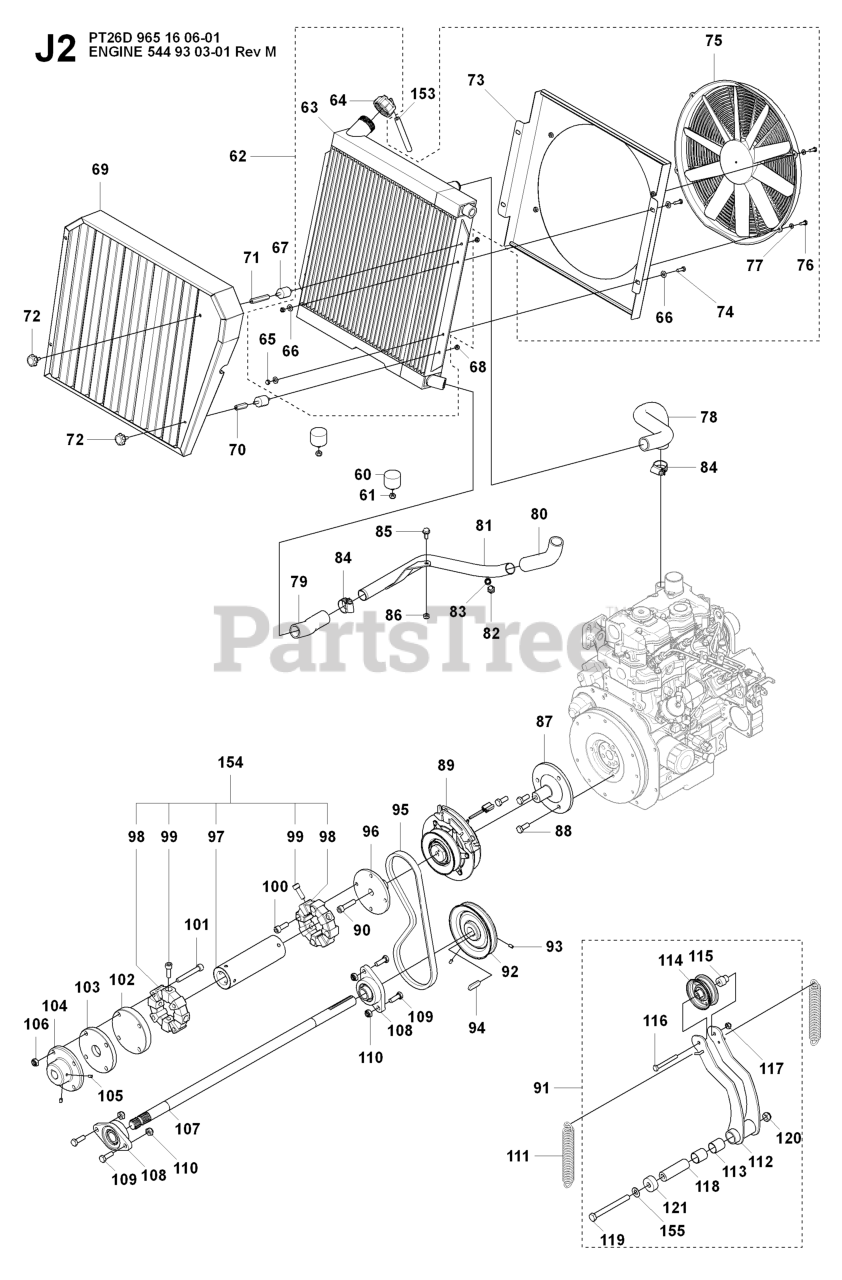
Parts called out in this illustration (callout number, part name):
2	ENGINE MOUNTING RIGHT
3	ENGINE MOUNTING LEFT
6	ANTIVIBRATION ELEMENT ENGINE
8	LOCKNUT M8
9	ANTIVIBRATION ELEMENT ENGINE
11	WASHER BRB 8.4X17
12	ANTIVIBRATION ELEMENT
20	BRACKET THROTTLE WIRE
23	BOLT
30	RP HOSE CLAMP FUEL HOSE
32	AIR CLEANER
34	HOSE AIR INTAKE
35	HOSE AIR INTAKE PT 26D 2006-20
38	LOCKNUT M8
39	CATALYTIC CONVERTER
41	LOCKNUT M8
45	HYDRAULIC PUMP
46	CONNECTION
47	SCREW M6S 6X20
49	FUEL FILTER
50	FILTER HOLDER WITH PRIMING PU
51	AIR FILTER
54	BRACKET AIR CLEANER
60	ANTIVIBRATION ELEMENT
61	LOCKNUT M8
62	RADIATOR ASSY
65	LOCKNUT M6
66	WASHER - 15X7.3X1.6
67	ANTIVIBRATION ELEMENT RADIATOR
68	LOCKNUT M6
75	ELECTRIC FAN
76	Screw
77	WASHER - M6
78	HOSE COOLING WATER
79	HOSE COOLING WATER
80	HOSE COOLING WATER
81	TUBE COOLING WATER
82	SCREW EHHM
86	LOCKNUT M8
87	POWER TAKE OFF
88	Screw M10x25
100	SCREW IHSCM M10X30 12.9 ZPB L
101	SCREW IHSCM 10X75 12.9 ZPB
106	NUT
108	BEARING UNIT FYTB 25TF
111	DRAW SPRING L=85,8
113	BUSHING
114	IDLER PULLEY
117	LOCKNUT M8
151	Screw M10x25
152	BOLT
